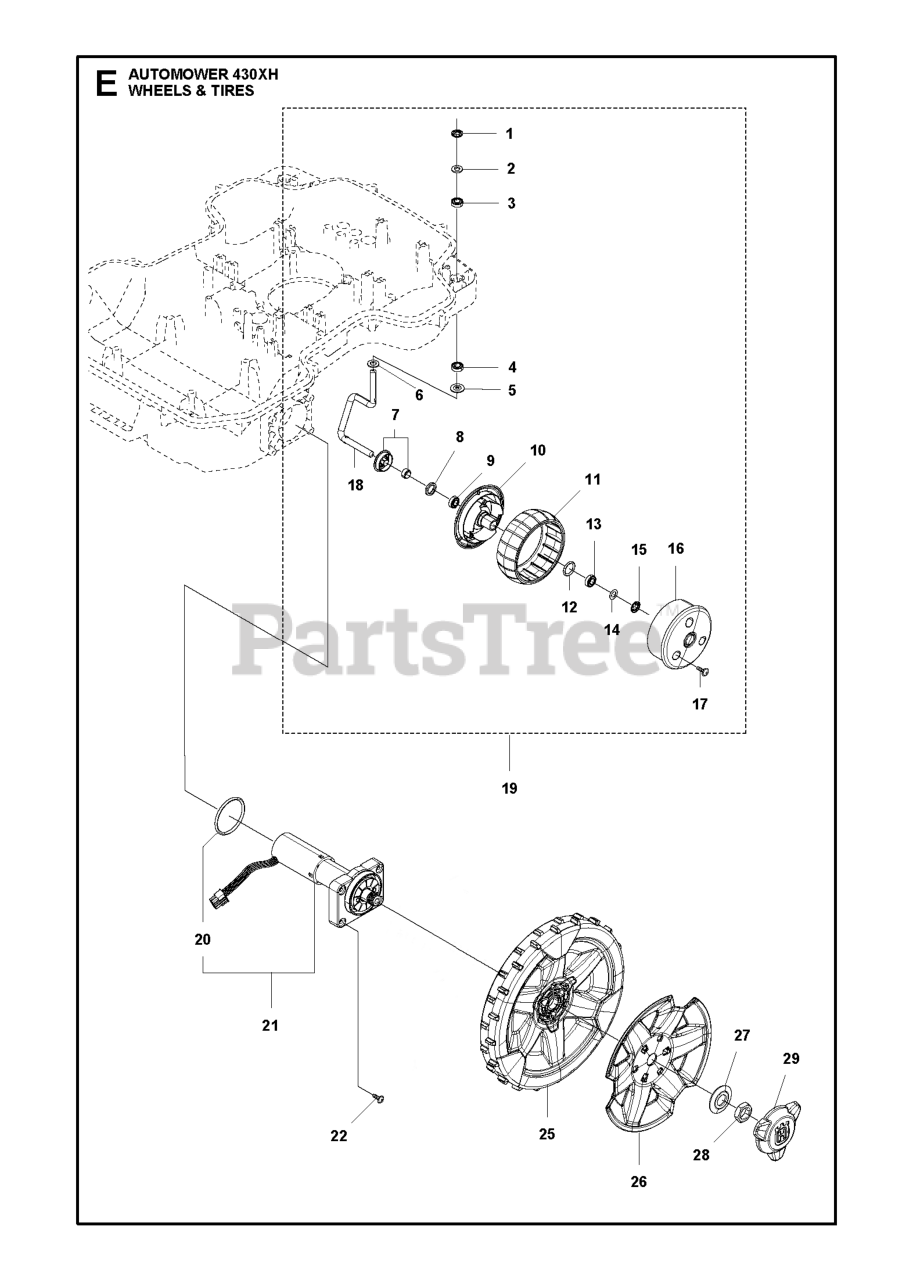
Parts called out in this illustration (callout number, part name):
1	LOCKWASHER PUSH-ON TYPE P 8 BV
2	WASHER DIN 988 13X8X0.5
3	BALL BEARING SINGLE ROW S688
4	BALL BEARING SINGLE ROW S688
5	WASHER FRONT WHEEL CENTER HOLE
6	WASHER DIN 988 13X8X0.5
7	SHIELD KIT
8	SEALING 12X18X3
9	BALL BEARING SINGLE ROW S688
10	WHEEL FRONT WHEEL INSIDE
11	WHEEL RUBBER TYRE
12	O-RING 2,62X15,54
13	BALL BEARING SINGLE ROW S688
14	WASHER DIN 988 13X8X0.5
15	LOCKWASHER PUSH-ON TYPE P 8 BV
16	WHEEL FRONT WHEEL OUTSIDE
17	SCREW 14MM
18	SPINDLE SPINDLE FRONT WHEEL RI
19	WHEEL KIT FRONT
20	O-RING LIGHT GREY
22	SCREW ITXPANT
26	WHEEL COVER REAR WHEEL
27	WASHER WASHER REAR WHEEL 16X40
28	HEXAGON THIN NUT
29	HUB CAP REAR WHEEL NO CENTER P
